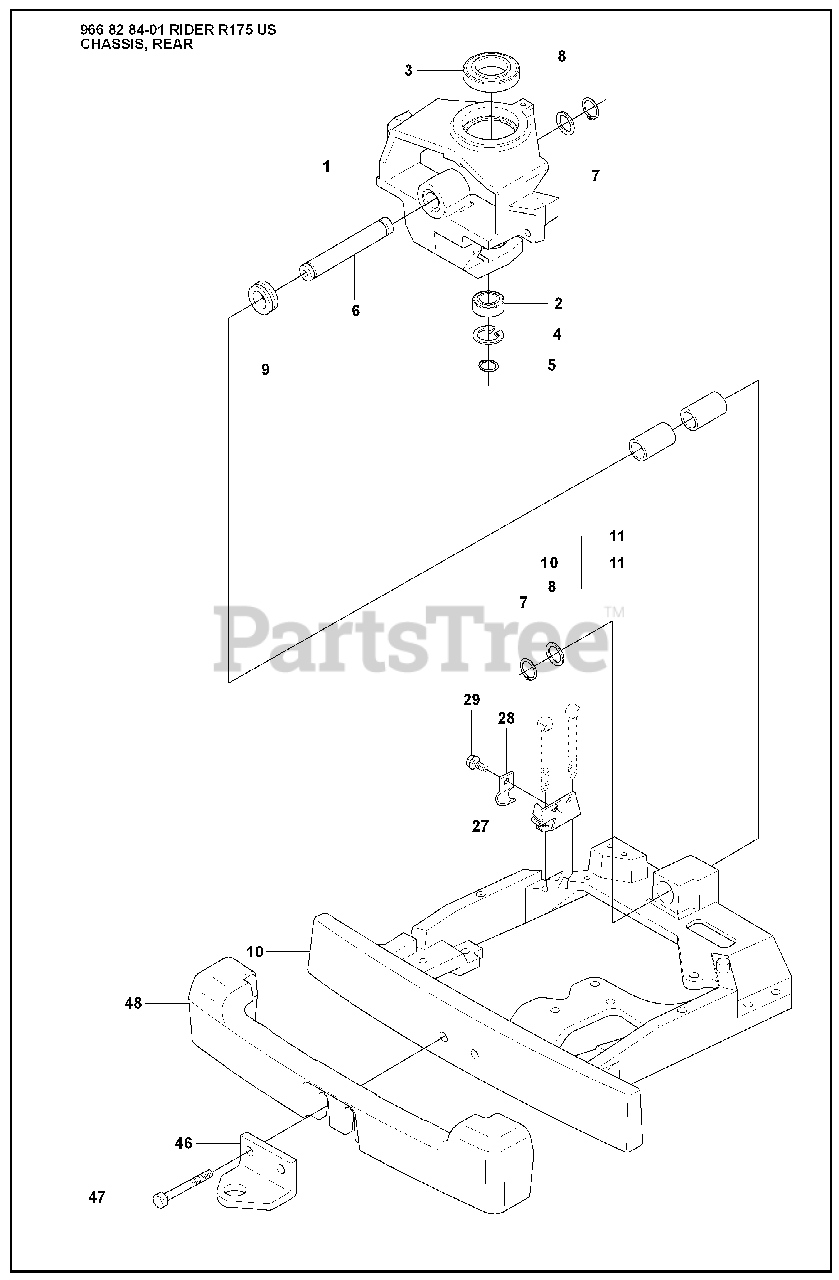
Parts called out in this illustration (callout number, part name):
2	Ball Bearing
3	BALL BEARING 6010 2RS1
4	CIRCLIP SGH 47
5	RETAINING RING SGA 25
7	RETAINING RING SGA 25
47	REPL BY 725 25 00-71
48	COUNTERWEIGHT
